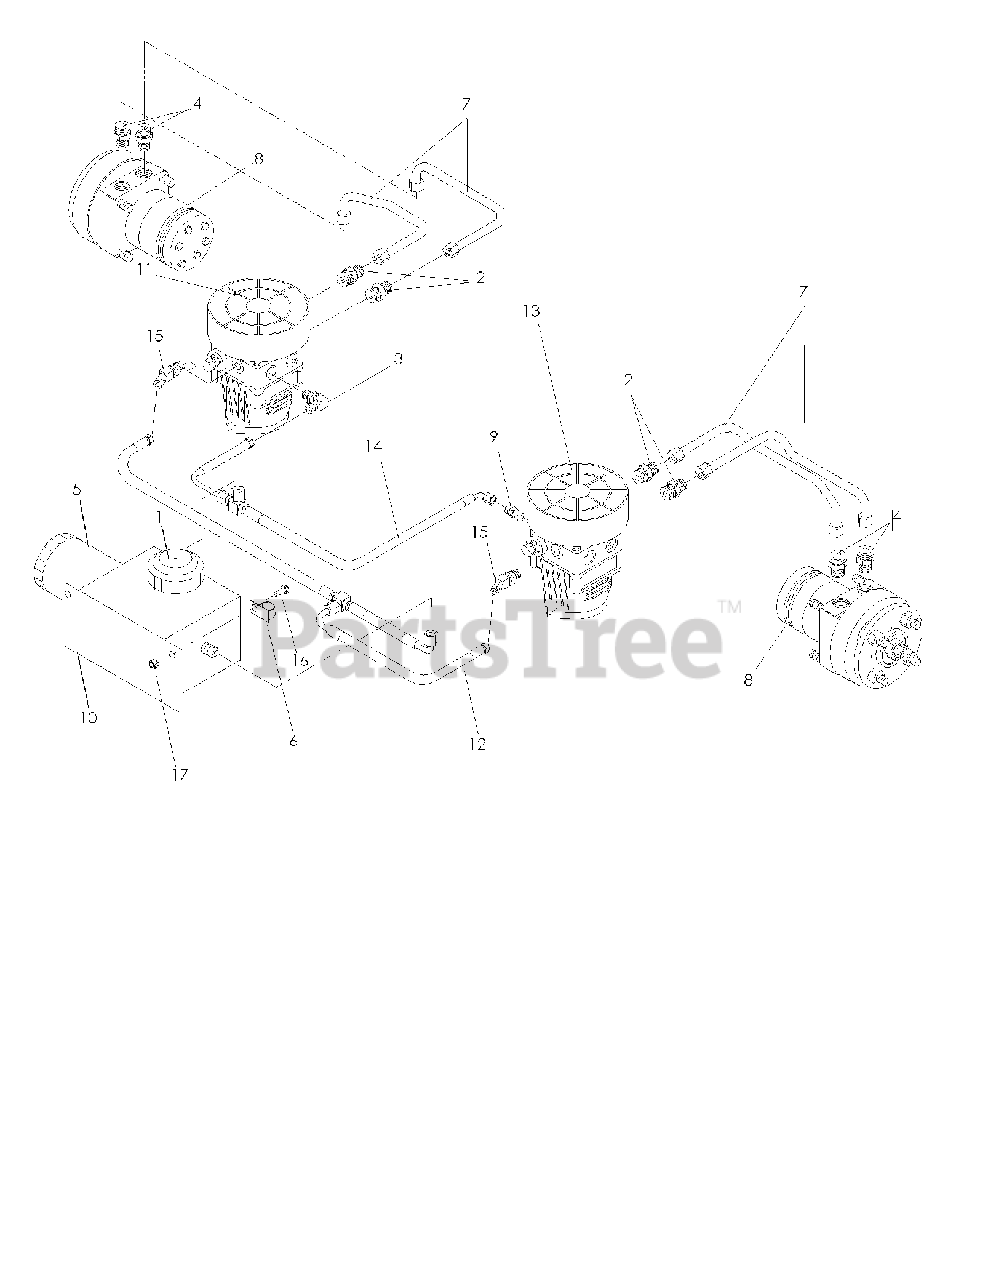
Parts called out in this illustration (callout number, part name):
1	HYDRAULIC CAP
2	FITTING, STRAIGHT F6400-8-8-0
3	ELBOW, F6801-6-6-0 90 DEGREE
4	FITTING
5	HYDRAULIC OIL FILTER
6	LOOM CLIP
7	RUBBER HYDRAULIC HOSE (1)
8	TL15 WHEEL MOTOR
9	Hydraulic Fitting
10	RESERVOIR W/CAP & FILTER
11	10CC PUMP W/6" FANS RH
12	T-ASM, INLET
13	10CC PUMP W/6" FANS LH
14	T-ASM, RETURN
15	FITTING, HYDR 45 DEG
16	HCS 5/16C X 3/4
17	NUT 5/16 NYLOC
